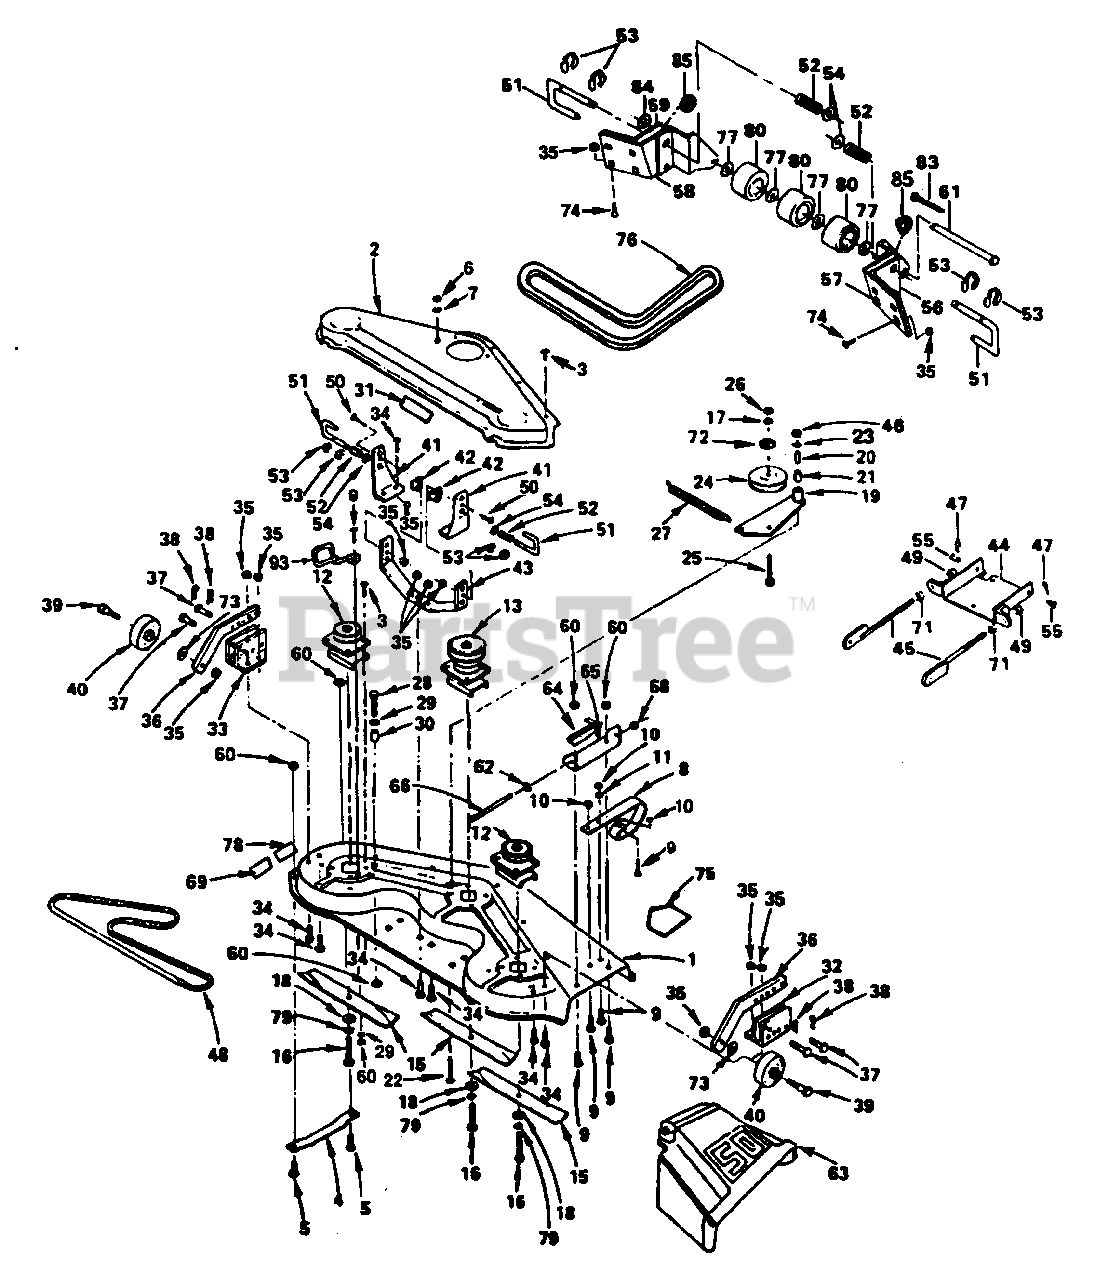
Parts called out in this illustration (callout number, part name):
1	Mower Housing (AYP part number)
2	Deck Drive Cover (AYP part number)
3	Thd. Roll. Washer Hex Screw (AYP part number)
4	L.H. Runner (AYP part number)
5	Carriage Bolt (AYP part number)
6	Lock Washer 5/16 (AYP part number)
7	Hex Nut 5/16-18 (AYP part number)
8	R.H. Runner (AYP part number)
9	Carriage Bolt
10	Locknut (AYP part number)
11	Washer 11/32 x 11/16 x 16 Ga. (AYP part number)
12	Secondary Mandrel (AYP part number)
13	Primary Mandrel (AYP part number)
14	Thd. Roll. Washer Hex Screw (AYP part number)
16	Hex Bolt 3/8-24 x 1-1/2 Gr. 5 (AYP part number)
17	Lock Washer 3/8 (AYP part number)
18	Washer (AYP part number)
19	Idler Arm Assembly (AYP part number)
20	Bearing Liner (AYP part number)
21	Bearing (AYP part number)
22	Carriage Bolt (AYP part number)
23	Washer (AYP part number)
24	Idler Pulley (AYP part number)
25	Hex Bolt 3/8-16 x 1-1/2 (AYP part number)
26	Hex Nut 3/8-16 (AYP part number)
27	Spring (AYP part number)
28	Hex Bolt 5/16-18 x 1-1/4 Gr. 5 (AYP part number)
29	Washer (AYP part number)
30	Split Spacer (AYP part number)
31	Dr. Schematic V-Belt Mower Decal (AYP part number)
32	R.H. Ga. Wheel Bracket (AYP part number)
33	L.H. Ga. Wheel Bracket (AYP part number)
34	Carriage Bolt 3/8-16 x 3/4 (AYP part number)
35	Crownlock Nut
36	Ga. Wheel Bar (AYP part number)
37	Clevis Pin (AYP part number)
38	Spring Retainer (AYP part number)
39	Shoulder Bolt (AYP part number)
40	Gauge Wheel (AYP part number)
41	Suspension Bracket (AYP part number)
42	Spacer (AYP part number)
43	Suspension Brace (AYP part number)
44	Mower Suspension Plate Assembly (AYP part number)
45	Suspension Bracket (AYP part number)
46	Hex Nut (AYP part number)
47	Spring Retainer (AYP part number)
48	V-Belt (AYP part number)
49	Crownlock Nut 1/2-13 (AYP part number)
50	Hex Bolt (AYP part number)
51	Release Pin (AYP part number)
52	Spring (AYP part number)
53	Klip Ring (AYP part number)
54	Washer (AYP part number)
55	Clevis Pin (AYP part number)
56	R.H. Outer Bracket (AYP part number)
57	R.H. Inner Bracket (AYP part number)
58	L.H. Inner Bracket (AYP part number)
59	L.H. Outer Bracket (AYP part number)
60	Locknut
61	Pivot Pin (AYP part number)
62	Washer (AYP part number)
63	Deflector Shield (AYP part number)
64	Deflector Spring (AYP part number)
65	Deflector Bracket (AYP part number)
66	Hinge Rod (AYP part number)
68	Push Nut (AYP part number)
69	Caution Instruction Decal (AYP part number)
71	Hex Nut (AYP part number)
72	Washer (AYP part number)
73	Washer (AYP part number)
74	Carriage Bolt (AYP part number)
75	Warning Decal (AYP part number)
76	V-Belt (AYP part number)
77	Washer (AYP part number)
78	Instruction Decal (AYP part number)
79	Lock Washer 3/8 (AYP part number)
80	Nose Roller (AYP part number)
83	Retainer Spring (AYP part number)
84	Washer (AYP part number)
85	Spacer (AYP part number)
93	L.H. Keeper (AYP part number)
